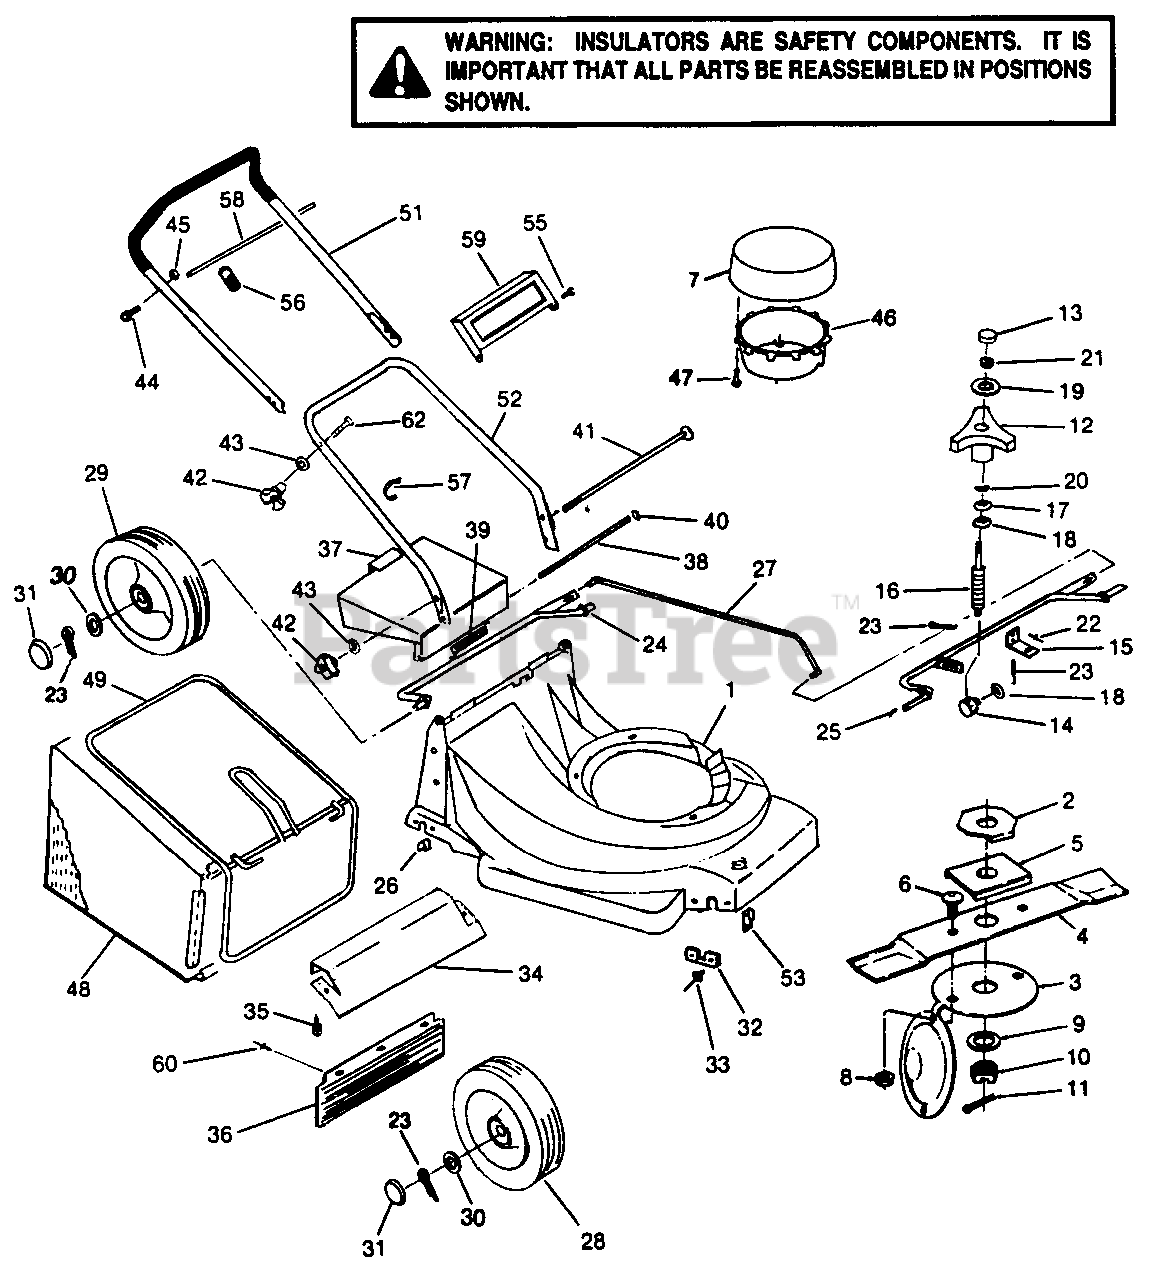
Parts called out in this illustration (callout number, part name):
1	Deck- 16" Molded
2	Blade Adapter
3	Blade Insulator
4	Blade- 16" Electric
5	Insulator - Adaptor
6	Carriage Bolt 5/16-18 x 3/4"
7	Motor Cover Top
8	Keps Nut 5/16-18
9	Washer (Special Heat Treated)
10	Slotted Hex Nut 1/2-20
11	Cotter Pin 3/32 x 1" (Special- Stainless Steel)
12	Knob - Height Adjust
13	Plug - Height Adjust Knob
14	Trunion - Height Adjust
15	Bracket-Screw Brace
16	Screw Shatt -Height Adjust
17	Washer
18	Washer
19	Washer
20	Spring Washer
21	Nut-Metric
22	Blind Rivet
23	Cotter Pin 3/32 x 3/4"
24	Rear Axle Assembly
25	Front Axle Assembly
26	Bushing - Axle
27	Link Rod - Height Adjust
28	Wheel - 7"
29	Wheel - 7"
30	Flatwasher 3/8"
31	Hub Cap
32	Retainer- Axle
33	Blind Rivet
34	Support- Deck & Trail Shield
35	Screw - M etric
36	Trail Shield
37	Chute Door
38	Hinge Pin
39	Spring - Chute Door
40	Pushnut Retainer
41	Pin - Lower H andle
42	Knob - Handle
43	Saddle Washer
44	Screw #10-24 x 1 1/4" Slotted Rd. Head
45	Nut #10-24 Locking
46	Motor Cover Bottom
47	Screw #10-16 x 3/4"
48	Grass Bag
49	Catcher Fram e Assembly
51	Upper Handle w/ Foam Grip
52	Lower Handle
53	Bracket- Axle Brace
55	Screw #10-16 x 3/4" Sheet Metal
56	Cord Minder
57	Plastic Tie
58	Rod - Cord Control
59	Trimplate
60	Blind Rivet
62	Saddle Bolt 5/16-18 x 2"
